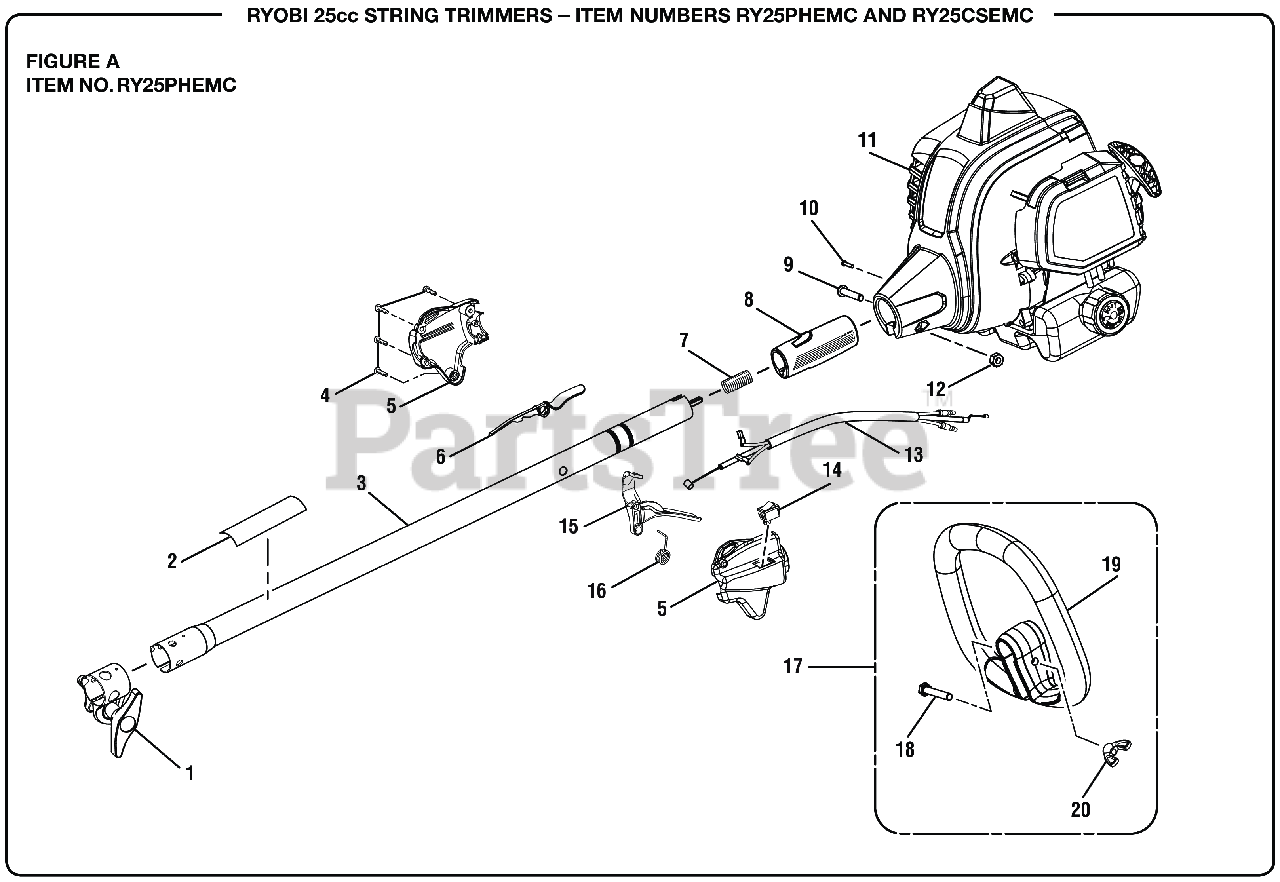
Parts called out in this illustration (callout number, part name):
1	Boom Clamp Assembly
2	Warning Icon Label
3	Upper Boom Assembly
4	Screw (M4 x 20 mm, T20 Torx Pan Hd. S.T.)
5	Control Handle Assembly (Inc. Key No. 6)
6	Trigger Lock
7	COMPRESSION SPRING
8	Rear Handle Grip
9	Screw (M6 x 30 mm, T27 Torx Button Hd.)
10	Screw (M4 x 8 mm, T25 Torx Pan Hd. T.F.)
11	Powerhead Assembly w/Labels
12	Hex Nut (M6.3 x 1)
13	Throttle Cable and Wire Assembly
14	Stop Switch (Momentary Contact)
16	Torsion Spring (Throttle Trigger)
17	Auxiliary Handle Assembly
18	Screw (1/4-20 x 40 mm, Cap Hex Hd.)
19	Front Handle
20	Wing Nut (1/4-20, Plastic)
